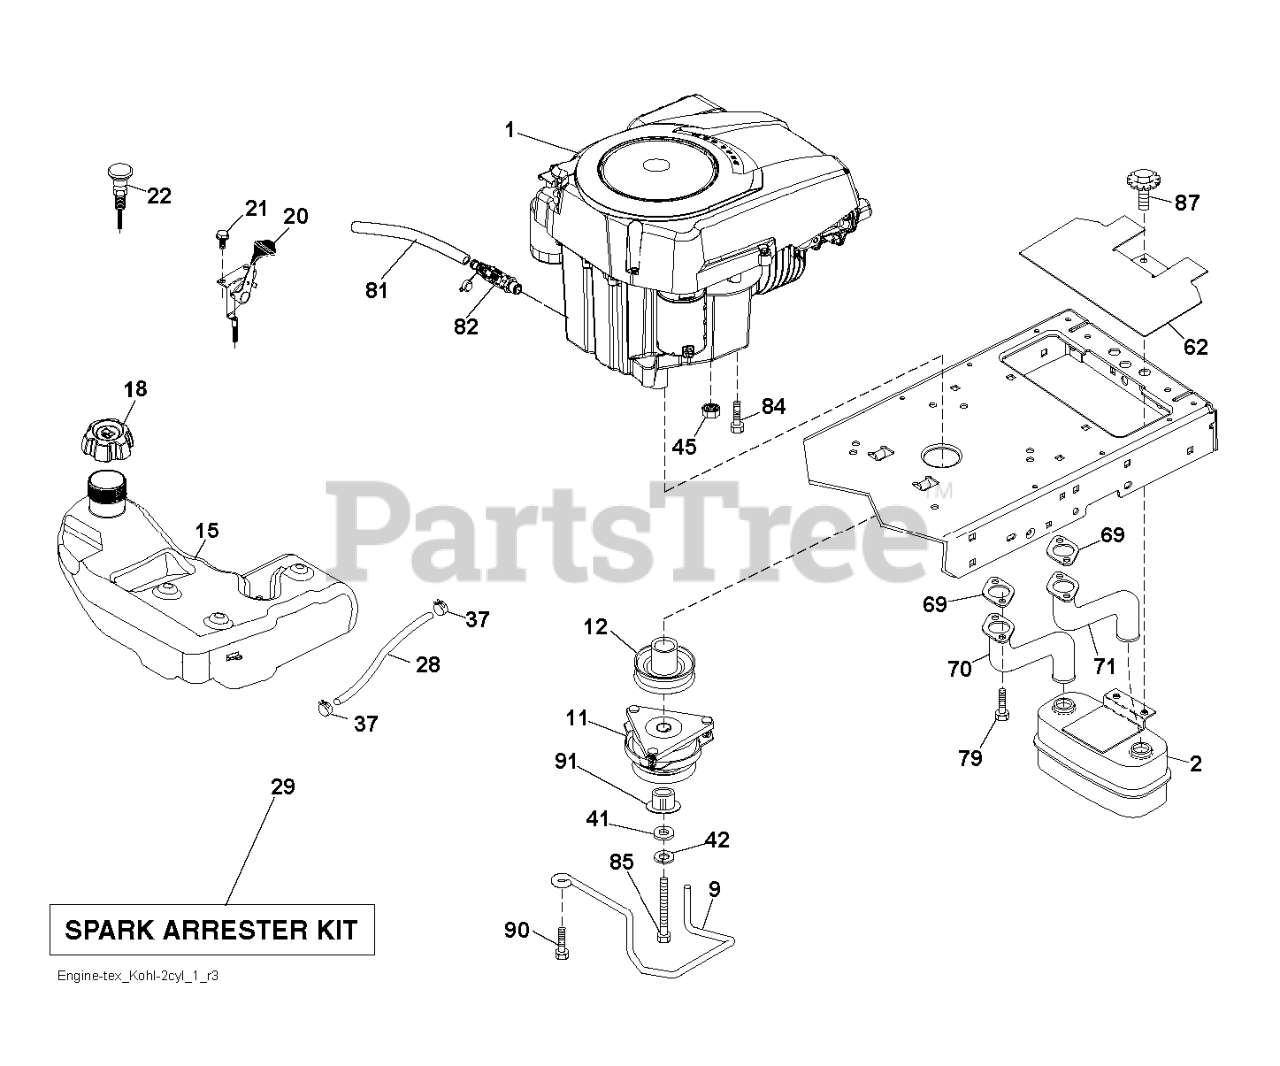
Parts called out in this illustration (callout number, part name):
2	MUFFLER.TWIN.CYL.LOW.TONE
9	KEEPER.BELT.ENGINE.4.2
11	CLUTCH MZ ZTR GT.48/54"1.125"
12	PULLEY ENGINE
15	TANK.FUEL.4GAL
18	RP CAP FUEL
20	THROTTLE CONTROL
21	SCREW.#10 X 0.750.BOS
22	CONTROL.CHOKE.ERGO.PUSH-IN.BLA
28	FUEL LINE 54"
29	KIT.SPARK ARRESTOR 794945 B&S
37	HOSE CLAMP
42	LOCKWASHER
45	NUT
62	RP SHIELD HEAT MUFFLER
69	GASKET.EXHAUST.KOHL.CV18-CV26
70	RP.PIPE-EXHAUST LH
71	RP.PIPE-EXHAUST RH
79	SCREW.SOCKET HD.5/16-1
81	TUBE, DRAIN OIL ASM.
82	VALUE.OIL.DRAIN
84	SCREW 3/8-16X1
85	BOLT HEX 7/16-20 X 3.75 GR. 5
87	BOLT.5/16-18UNCX1.W/SEMS.BLK
90	SCREW 3/8-16X1
91	BUSHING.1.375OD
